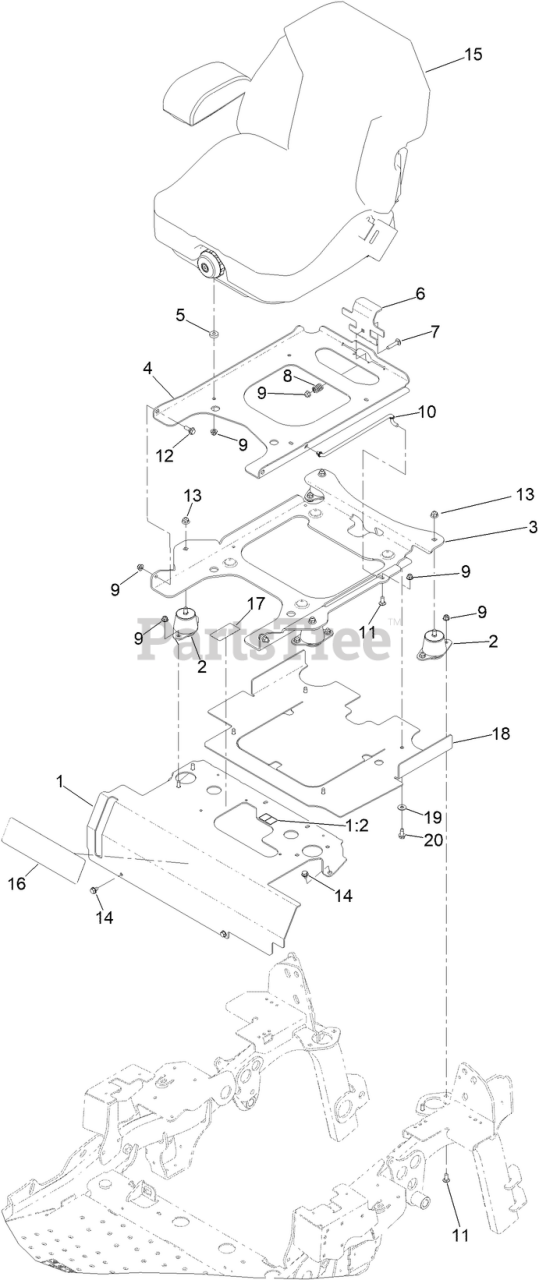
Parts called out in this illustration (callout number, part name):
1	MOUNT-SEAT W/DECALS
1:2	DECAL-WARNING
2	ISOLATOR-SEAT
3	PLATE,TILT SEAT SUPPORT
4	PLATE-FRAME, SEAT
6	PLATE, SEAT LATCH
7	BOLT-CARR
8	SPRING-COMPRESSION
9	NUT-HF, NI
10	ROD-PROP
11	SCREW-CARR
12	SCREW-SHOULDER
13	NUT-HF, NI
14	SCREW
15	SEAT-SUSPENSION
16	DECAL-CONSOLE
17	DECAL-FLUID, TRANSMISSION
18	SHIELD-HEAT
19	WASHER-FLAT
20	SCREW-HWHTF
